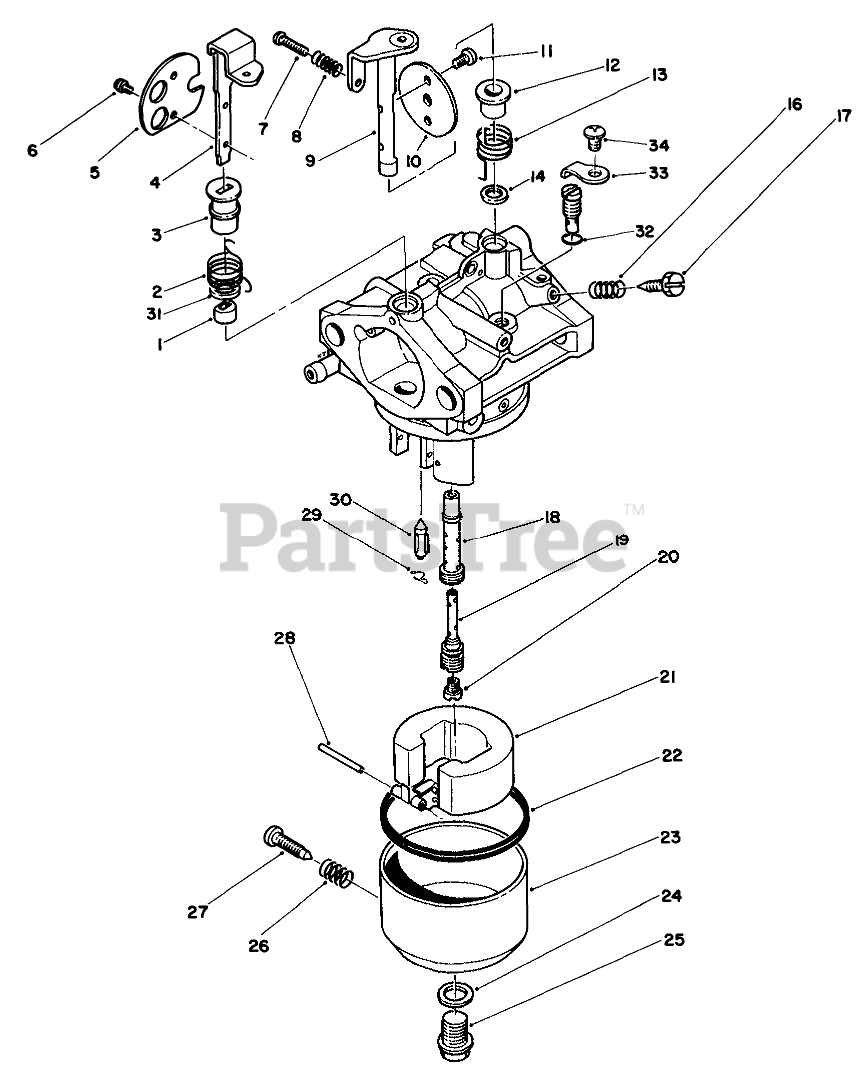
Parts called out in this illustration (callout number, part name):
1	Ring
4	Shaft-Choke
5	Valve-Choke
9	Shaft-Throttle
10	Valve-Throttle
14	Seal
19	Pipe-Bleed
22	Gasket
23	Chamber-Float
25	Bolt
27	Screw
28	Pin
29	Clip
30	Valve-Needle
